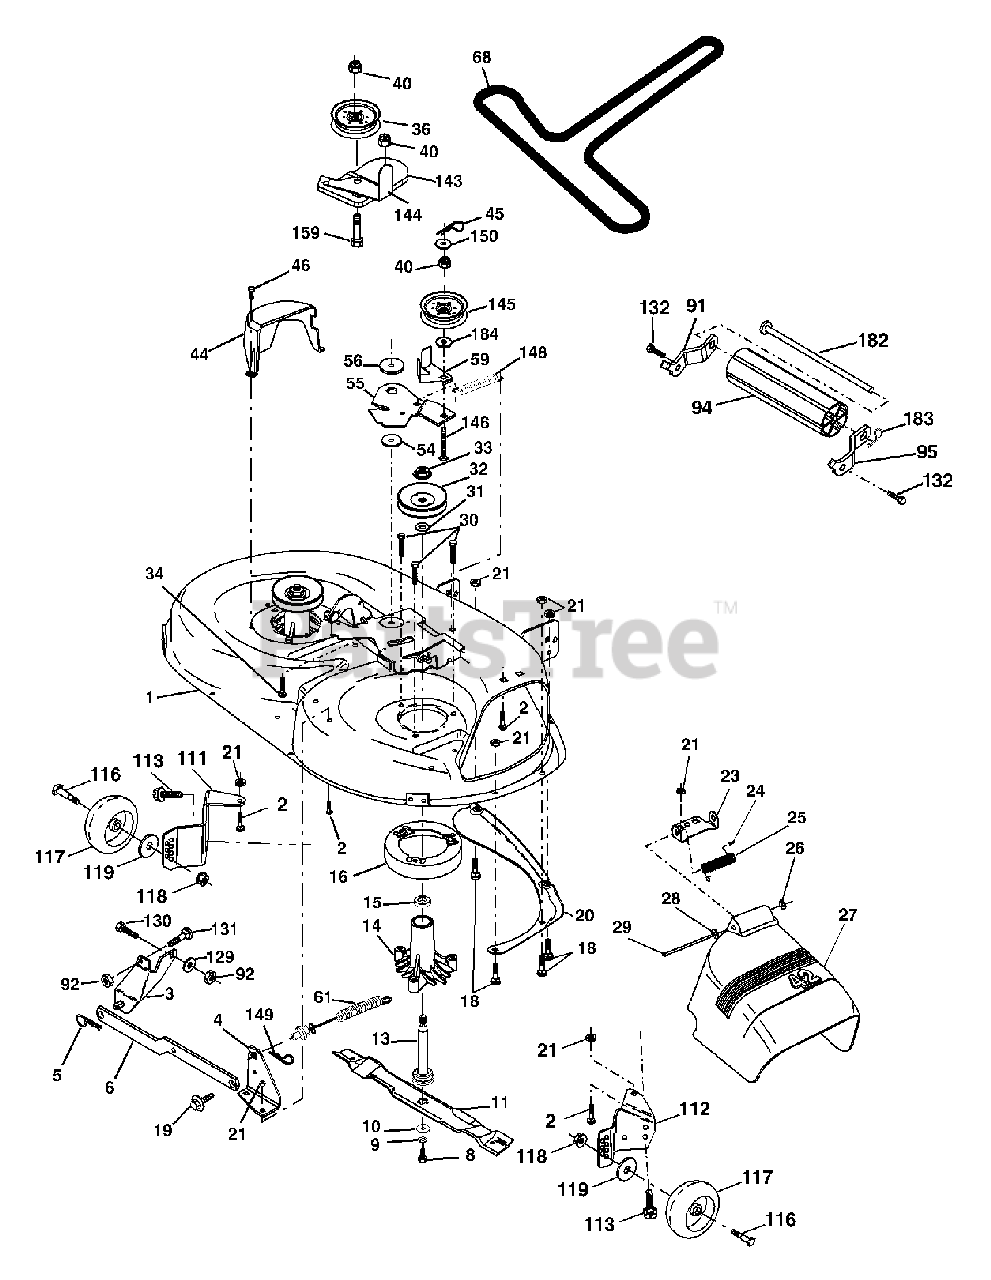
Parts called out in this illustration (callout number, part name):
1	Mower Deck Assembly, 42"
2	Bolt
3	Bracket Asm Fr. Sway Bar 3/42
4	Bracket Asm Deck 42" Sway Bar
5	Retainer Spring
6	Bar Sway Deck
8	Bolt 3/8-24 x 1.25 Gr. 8 patched
9	Washer, Lock
10	Washer, Hardened
11	Blade Mower 42" Hi-Lift
11	Blade, Mulching 42" Std
11	Blade Mulching 42" Premium
13	Shaft Assembly, Mandrel, Vented
14	Housing, Mandrel, Vented
15	Bearing, Ball, Mandrel
16	Stripper, Mandrel Deck
18	Bolt, Carriage 5/16-18 x 5/8
19	Bolt, Shoulder
20	Baffle, Vortex
21	Nut
23	Bracket, Deflector Mower 42"
24	Cap, Sleeve 80 x 1/2 Blk Mower
25	Spring, Torsion, Deflector 2 52
26	Nut, Push Phos & Oil
27	Shield, Deflector 42" Blk
28	Washer 11/32 x 5/8 x 16 Ga.
29	Rod, Hinge 42" 6 75 W/G
30	Screw Thdrol
31	Washer, Spacer Mower Vented
32	Pulley, Mandrel
33	Nut, Toplock
34	Bolt Carr SH 3/8-16 x 1-1/2 Gr.5
36	Pulley, Idler, Flat
40	Nut Lock 3/8-16
44	Guard, Mandrel, LH
45	Retainer
46	Screw, Thdrol 1/4-20 x 5/8 T
54	Washer, Hardened
55	Arm, Idler
56	Spacer, Retainer
59	Guard TUV Idler
61	Spring Ext Elect. Clutch
68	V-Belt, 42" Mower
91	Bracket Roller Nose RH
92	Nut Lock Hex W/lns 3/8-16 unc
94	Roller Nose
95	Bracket Roller Nose RH
111	Bracket Wheel Gauge LH
112	Bracket Wheel Gauge RH
113	Screw 5/16-18
116	Bolt, Shoulder
117	Wheel, Gauge
118	Nut Centerlock 3/8-16
119	Washer 3/8 x 7/8 x 14 Ga.
129	Washer 13/32 x 13/16 x 12 Ga.
130	Bolt Fin HEx 3/8-16 unc x 1 Gr. 5
131	Bolt RDHD SANK 3/8-16 unc x 1
132	Screw Hexwsh Thdrol
143	Bracket Arm Idler 42"
144	Keeper Belt 42" Clutch Cable
145	Pulley Idler Flat
146	Bolt Carriage Idler
148	Spring Return Idler
149	Retainer Spring Yellow
150	Washer 9/32 x 3/4 x 10 Ga.
159	Bolt Rdhd Sqn 3/8-16 unc x 1-3/4
182	Rod Roller Nose
183	Retainer Spring
184	Washer 13/32 x 7/8 x 10 Ga.
